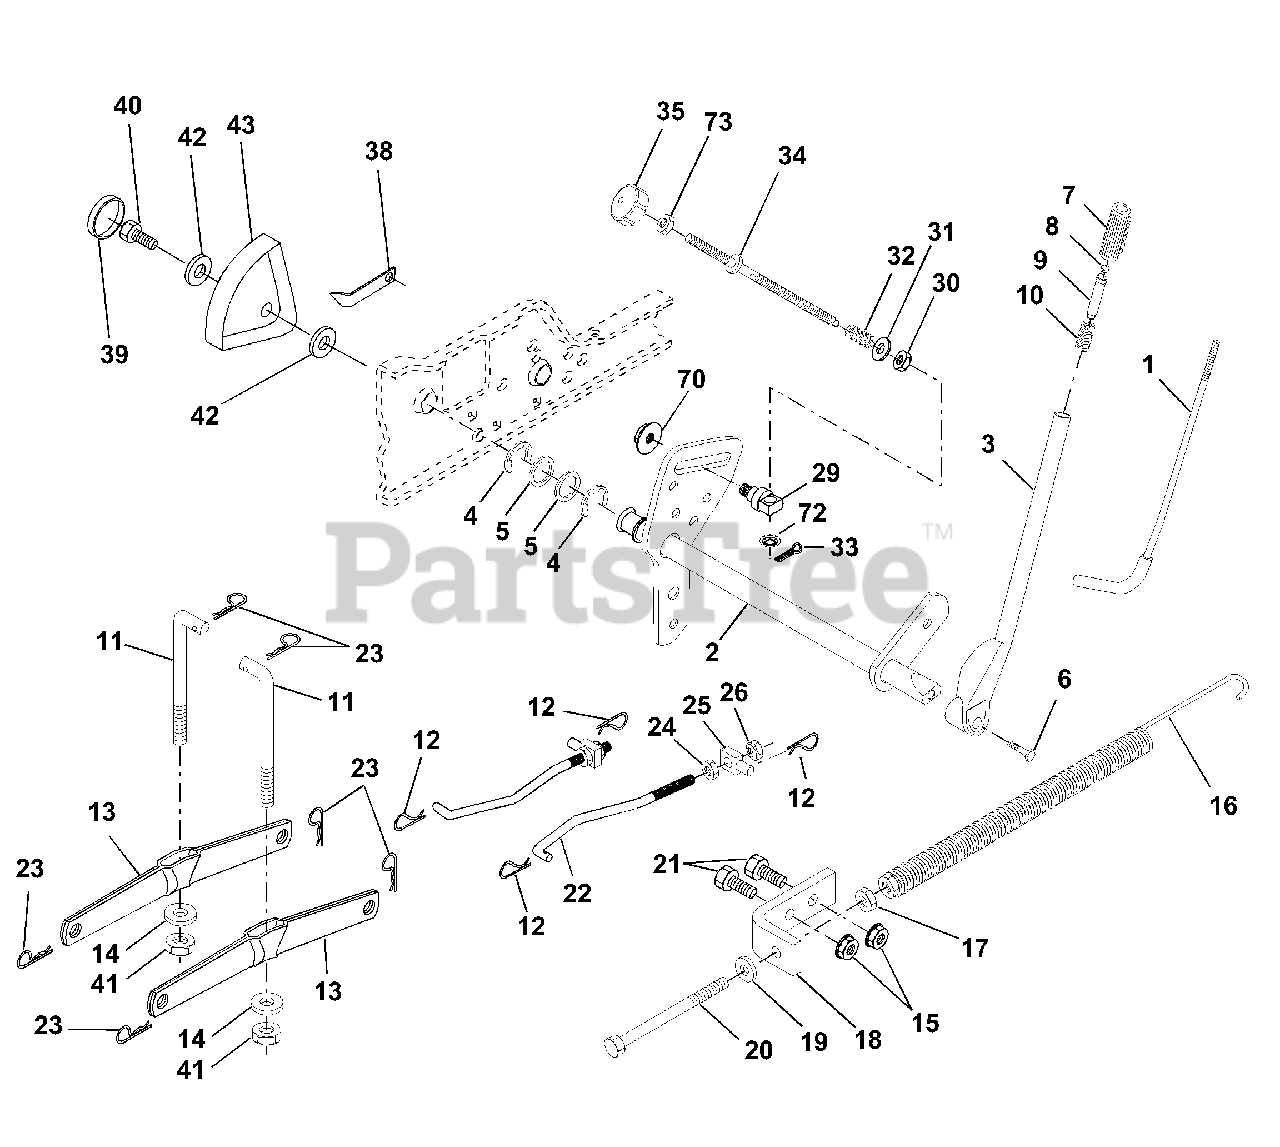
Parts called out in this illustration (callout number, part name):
1	Rod Asm., Lever
2	Shaft Asm., Lift Vgt
3	Lever Asm., Lift Rh
4	E-Ring Truarc #5133-87
5	Washer 29/32 x 1-1/4 x 16 Ga.
6	Bolt, Fin Hex 3/8-16 x 1-1/2
7	Grip, Handle Fluted
8	Button, Plunger
9	Plunger, Lever Lift
10	Spring 2-1/8"
11	Link Lift
12	Retainer, Spring
13	Arm, Suspension Vgt
14	Bearing
15	Nut, Crownlock 3/8-16 Unc
16	Spring Asm., Assist Lift
17	Nut, Hex Jam 3/8-16 Unc
18	Bracket, Spring Assist
19	Washer 13/32 x 13/16 x 16 Ga.
20	Bolt, Adjust Spring Assist
21	Bolt, Fin Hex 3/8-16 x 1
22	Link, Front
23	Retainer, Spring
24	Nut, Jam Hex 1/2-13 Unc
25	Trunnion
26	Nut, Crownlock 1/2-13 Unc
29	Trunnion, Infin Height
30	Nut, Special
31	Washer 13/32 x 5/8 x 16 Ga.
32	Spring, Compression Inf Hgt
33	Pin, Cotter 3/32 x 1/2
34	Rod, Adj Lift
35	Knob, Inf 3/8-16 Unc
38	Pointer, Height Indicator
39	Plug, Hole
40	Screw 5/16-18 x 1
41	Nut, Crownlock 3/8-24
42	Washer 11/32 x 1-1/2 x 10 Ga.
43	Scale, Indicator Height
70	Nut Hex Flange Lock
72	Nut Push Phos & Oil
73	Nut Hex Jam 3/8-16 Unc
